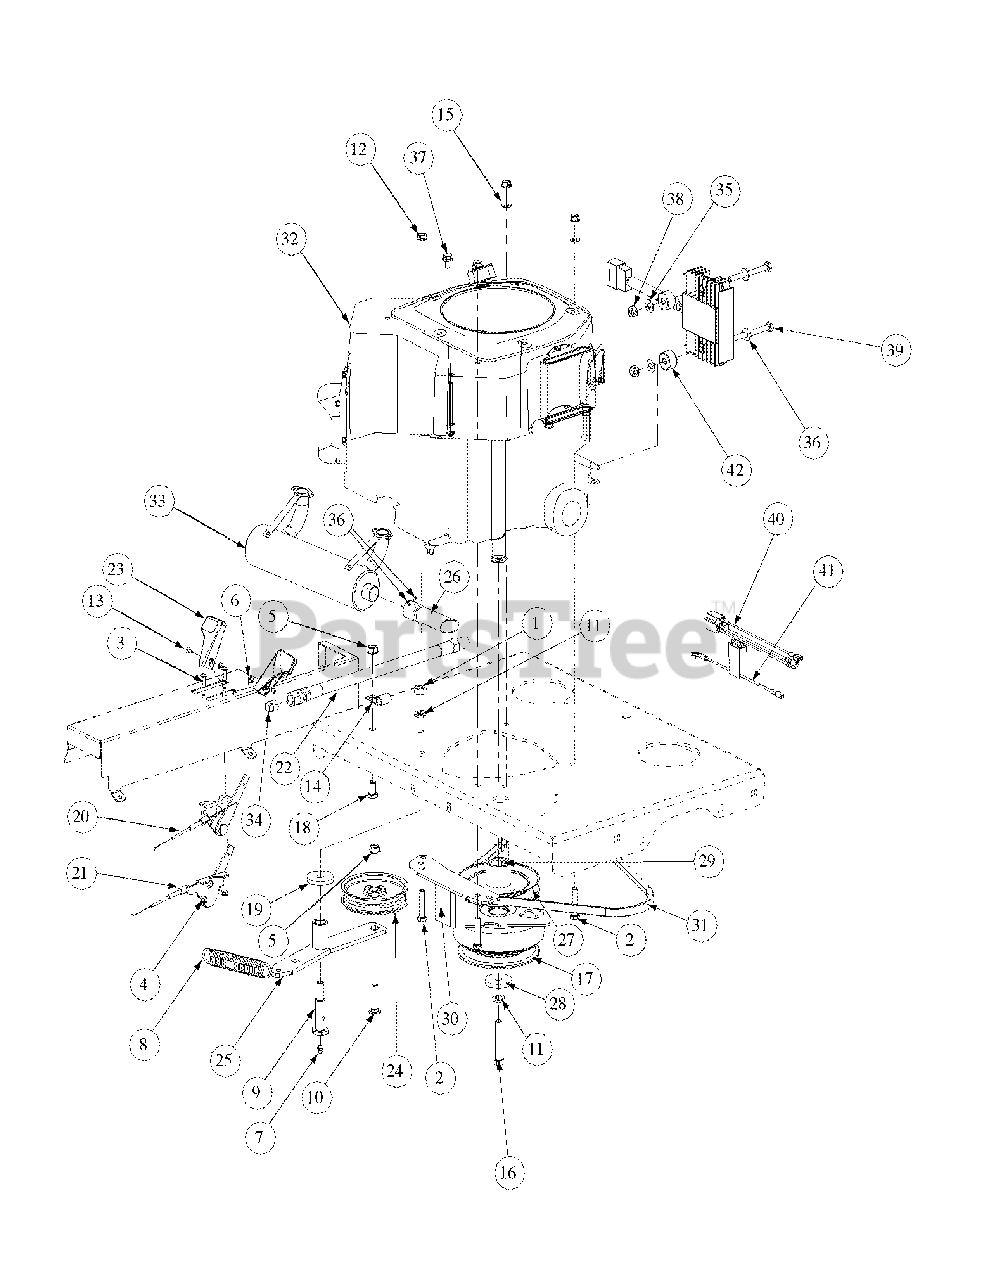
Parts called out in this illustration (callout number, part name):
1	Hex Nut, 7/16-14
2	HHCS, 5/16-18, 1-3/4
3	Round Hd. Machine Screw, 10-32 x 3/4
4	Lock Nut, Nylon Insert, 10-32
5	Flange Lock, Hex Nut, 3/8-16
6	Nut Washer, W/Star, 8-32
7	Grease Fitting, 1/4-28 x 3/16
8	Extension Spring, 1.0 OD x 5.00
9	Shoulder Screw, 7/16-14
10	Hex Carriage Screw, 3/8-16, 1.75
11	Lock Washer, 7/16
12	Hexflange Lock Nut, 5/16-18
13	Machine Screw, 8-32, .375
14	Clip, Heat Shield Cable
15	Flat Washer, 5/16
16	Capscrew, 7/16-20 x 3.50
17	Clutch Electric, Ogura JD08
18	Hex Cap Screw, 3/8-16, .750
19	Flat Washer, 7/16 ID x 1.75 OD x .25
20	Choke Control Cable
21	Throttle Control Cable
22	Oil Drain Hose
23	Control Throttle Knob
24	Flat Pulley with Flanges
25	Engine Idler Arm Casting
26	Straight Exhaust Pipe
27	Trans Drive Pulley
28	Flat Washer, 7/16 ID x 1.75 OD x .25
29	Key, 1/4 x 1/4 x 2.75
30	Retainer Clutch Assembly, Ogura
31	Belt, 51.2 Lg
32	Engine, 20HP Honda
33	Muffler
34	Pipe Plug, 3/8 NPT
35	Flat Washer, 1/4
36	Screw, 8-32 x 0.375
37	Screw, M6 x 1.0 x 12mm
38	Nut, 1/4-20, Hex Flange Lock
39	Hex Cap Screw, 1/4-20 x 2.50
40	Wire Harness Adapter
41	Charge Regulator Wire
42	Spacer, .281 ID x .875 OD
